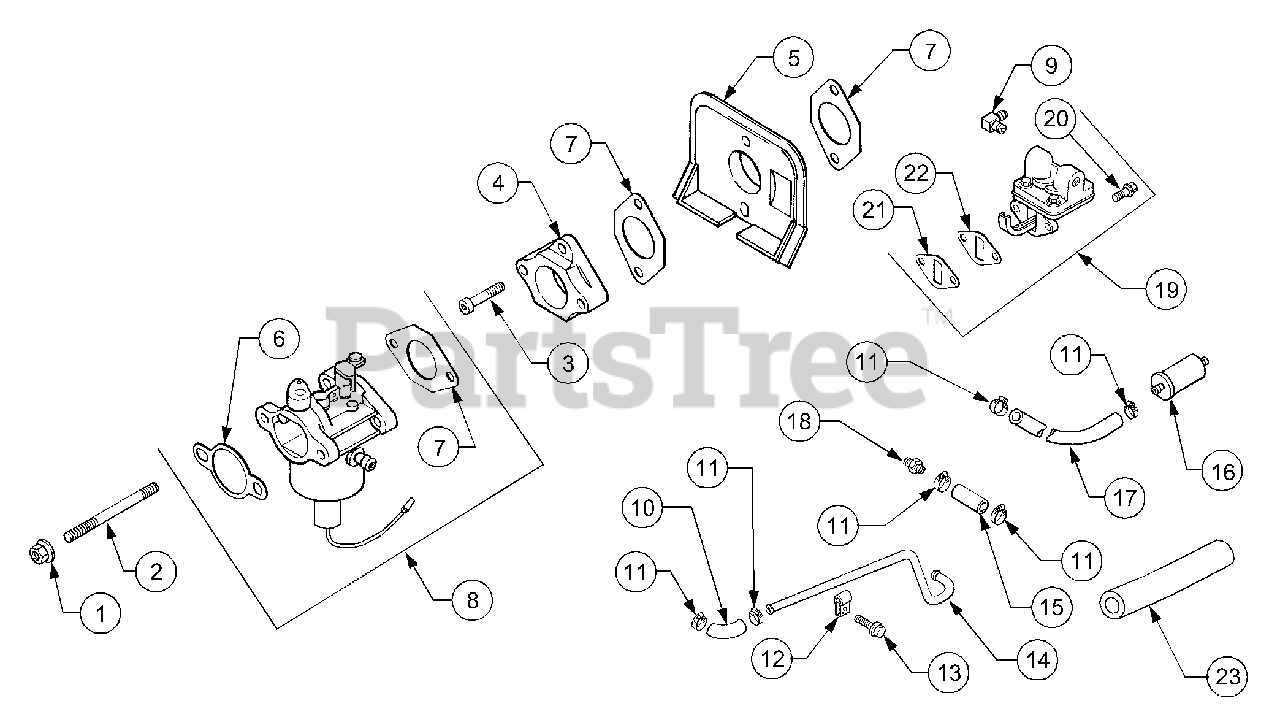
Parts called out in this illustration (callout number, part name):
1	Nut, Hex Flange, M6 x 1.0
2	Stud, Carburetor, M6 x 1.0 x 116
3	Screw, Socket Cap, M6 x 1.0 x 35
4	Adapter, Carburetor
5	Deflector, Heat
6	Gasket, Air Filter
7	Gasket, Carburetor
8	Kit, Carb w/Gskts
9	Connector, Hose, 90°.
10	Line, 90° Fuel
11	Clamp, Fuel Line
13	Screw, Hex Flange, M5 x .8 x 10
14	Line, Metal Fuel
15	Line, Fuel, 1 1/4
17	Line, Fuel, 5"
18	Connector, Straight Hose
19	Kit, Fuel Pump
20	Screw, Hex Flange, M6 x 1 x 20
21	Spacer, Fuel Pump
22	Gasket, Fuel Pump
23	Insulation, Fuel Line
